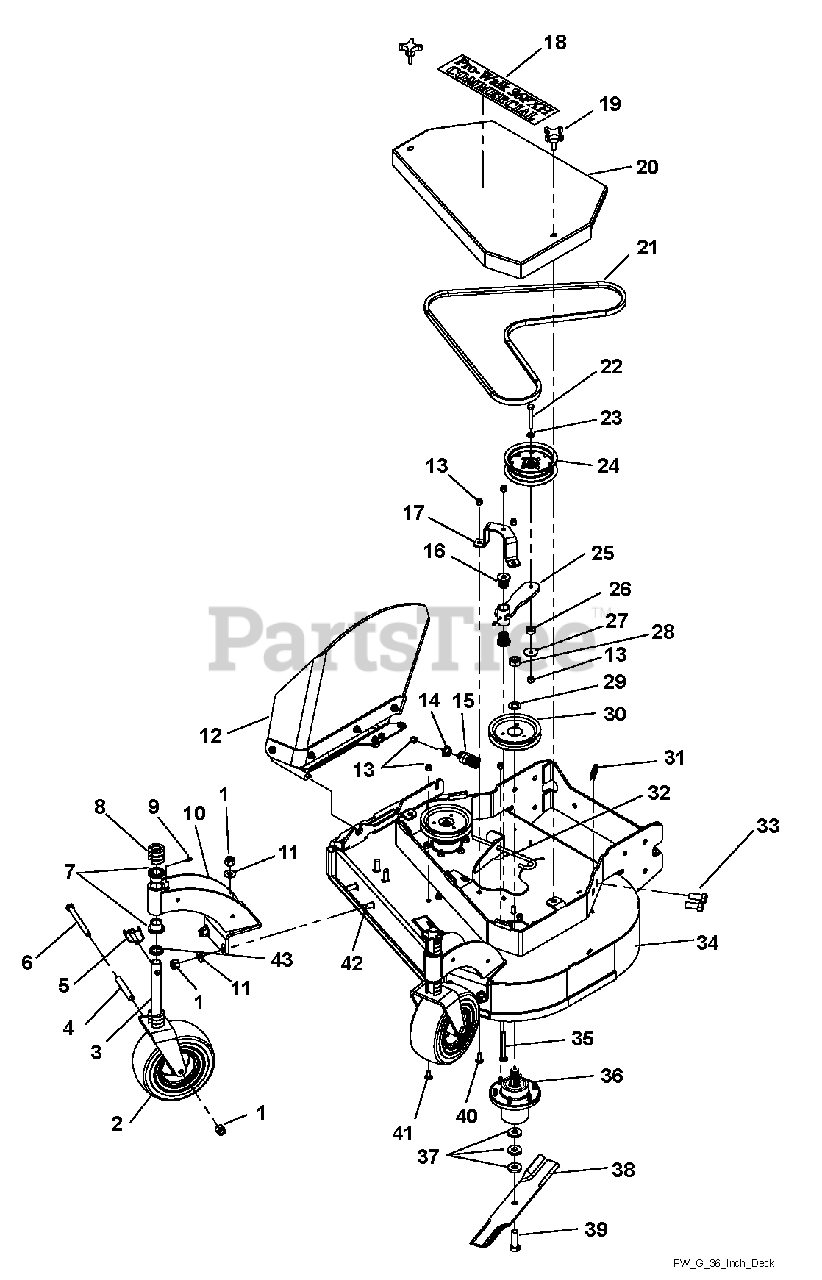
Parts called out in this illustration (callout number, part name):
1	Locknut, .50-13 Nyloc
2	Assembly, Wheel and Tire 9 x 3.5
3	Weldment, Caster Yoke w/Gravely Paint
4	Bolt, .50-13 x 5.50 Hex Grade 5
5	Pin, LNC .438 x 2.00
6	Bolt, 50-13 x 5.50 Hex Grade 5
7	Bearing, Flange 1.00 x 1.25 x 1.00
8	C-Spacer, 1.00 x 1.77 x .500
9	Fitting, .25-28 Straight Grease Zerk
10	Weldment, Strut Front FXWLK w/Gravely Paint
11	Washer, .438 Regular Flat
12	Discharge Shield Assembly
13	Locknut, .38-16 Nyloc
14	Keeper, Spring
15	Spring, COM 1.22 x .162 x 2.50
16	Bearing, Flange M10 x M25 x M27 Fluted
17	Brace, Tensioner Arm
18	Decal, Pro-Walk Commercial 36 FXH
19	Knob, .375 x 1.25-4 Prong
20	Weldment, Belt Shield 36"
21	Belt, HB 77.5 Elbow AMD OHR
22	Bolt, .38-16 x 2.75 Hex Grade 5
23	Washer, .406 x .813 x .065 Flat
24	Pulley, Flat 5.0 x .38 w/BRG
25	Weldment, Idler 36 FXWLK
26	Bushing, .380 x 1.00 x .410
27	Washer, Flat .375 x 1.50 x .063
28	Locknut, .75-16 Crown
29	Washer, .75 x 1.313 x .113
30	Pulley, Spline Spindle Offset
31	Trim, 1/4" Trim-LOK
32	J-Bolt, .375-16 x 7.88
33	Bolt, Hex .625-11 x 1.50 Grade 8
34	Assembly, Deck 36" Gravely w/Decal
35	Bolt, .375-16 x 3.50 Round Head Square Neck Grade 5
36	Assembly, Spindle Housing
37	Washer, Blade
38	Blade, 18.000 x .80 Lift
39	Bolt, .625-11 x 2.00 Hex 8
40	Bolt, .375-16 x 1.00 Round Head Square Neck Grade 5
41	Bolt, .38-16 x .75 Round Head Square Neck Grade 5
42	Bolt, Round Head Square Neck .50-13 x 1.50 Grade 5
43	Bushing, 1.03 x 1.50 x .179
